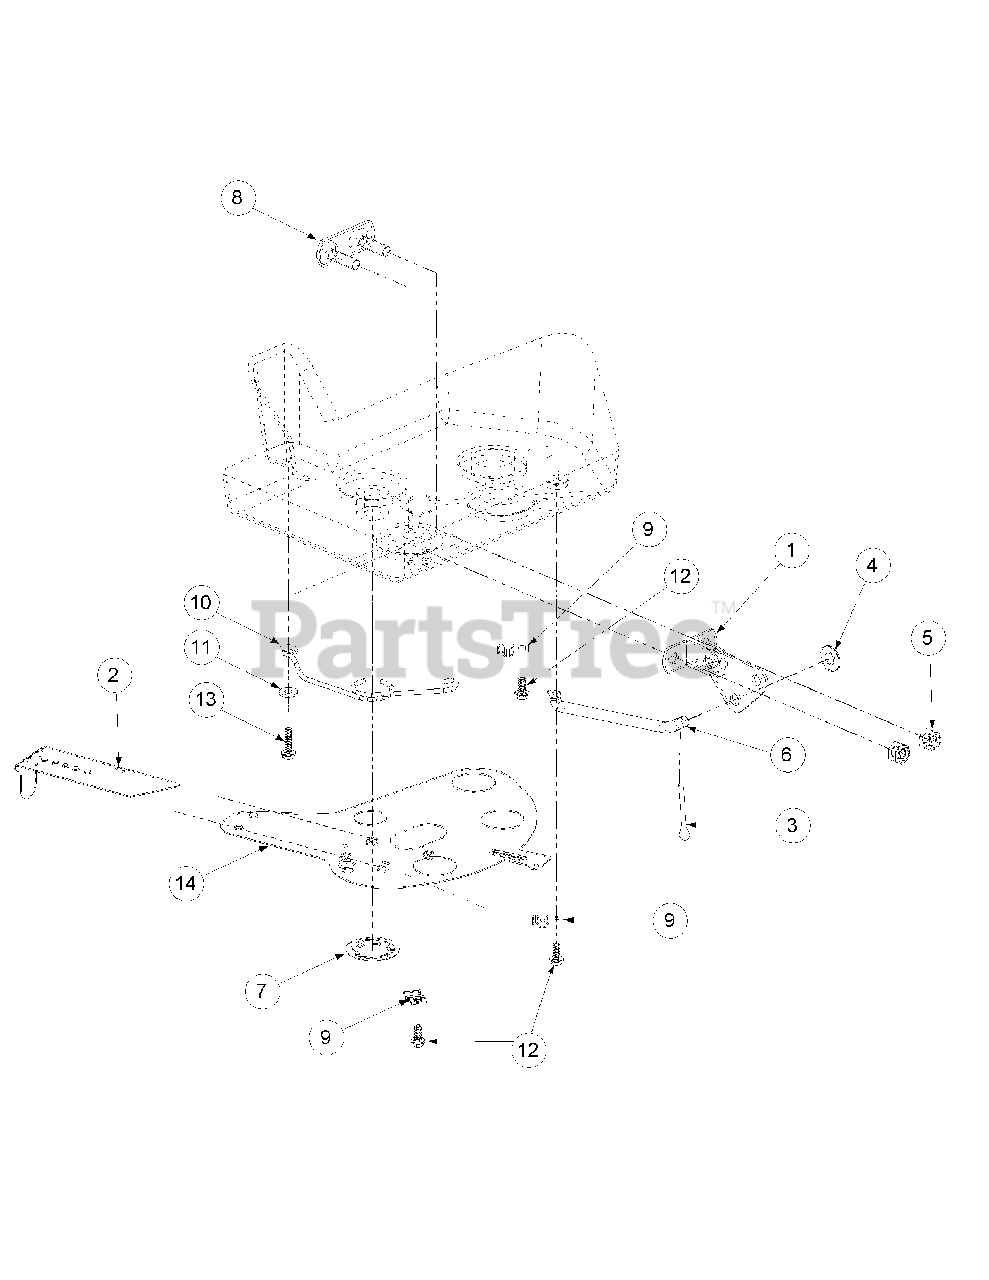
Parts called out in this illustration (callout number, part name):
1	Pivot Lever Assembly
2	Slide Lever
3	Cotter Pin, 3/32 x 1/2 Lg, SS
4	Flat Washer, 1/4"
5	Nylock Nut, 1/4-20
6	Pivot Lever Rod
7	Spring Clip
8	Two Hole Weldment Plate
9	Plate Shut-off Clip
10	Plate Shut-off Spring
11	Flat Washer
12	Index Washer Hex Screw, 8 x 3/8
13	Index Washer Hex Screw, 8 x 5/8
14	Shut-off Plate
